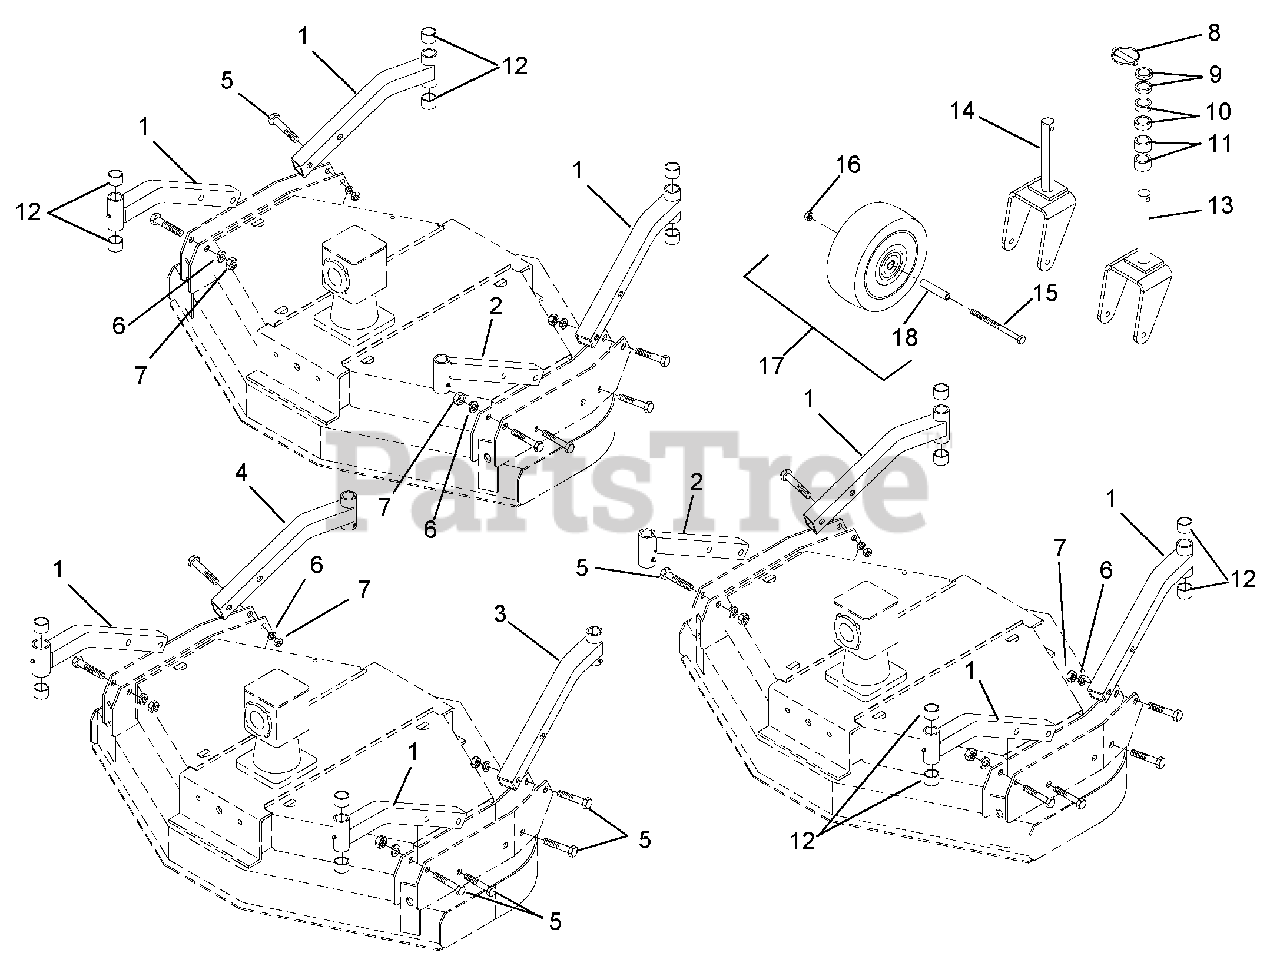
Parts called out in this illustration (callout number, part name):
1	Assembly, Arm
2	Weldment, Hex Arm
3	Weldment, Right Hand Hex Arm
4	Weldment, Left Hand Hex Arm
5	Cap Screw, Hex Head .62-11 x 3.5
6	Washer, Lock .625
7	Nut, Hex .625-11
8	Pin, Lynch
9	Spacer .25
10	Spacer .50
11	Spacer 1.00
12	Bushing, Bronze 1.25 x 1.50 x 1.00
13	Weldment, Caster – Round
14	Weldment, Caster – Hex
15	Cap Screw, Hex Head .50-13 x 6
16	Nut, Lock .50-13
17	Assembly, Pneumatic Tire and Wheel
18	Spacer, Wheel
